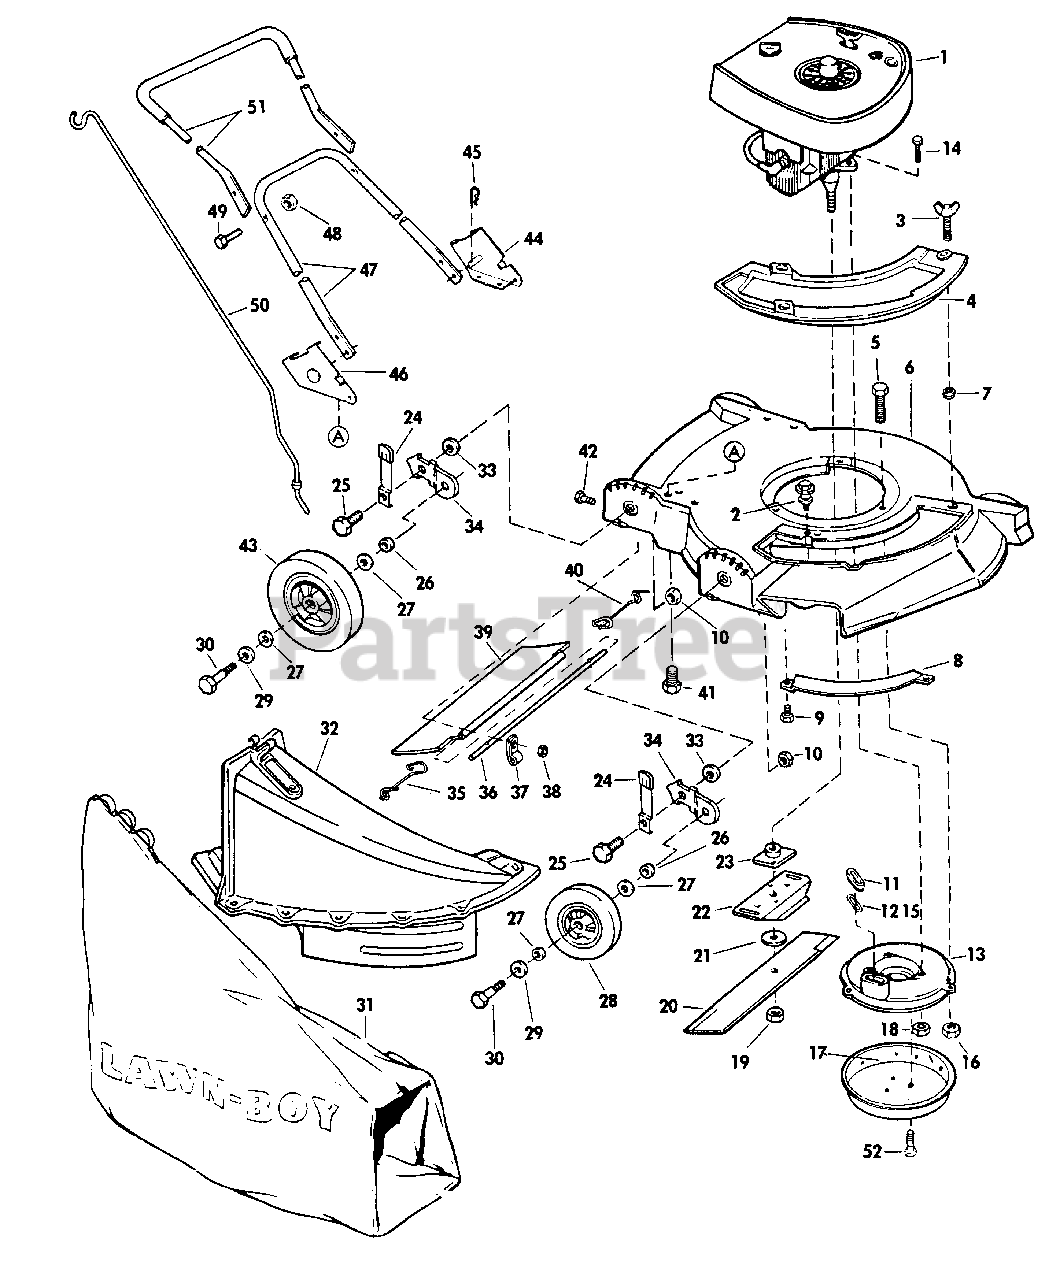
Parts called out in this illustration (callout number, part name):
1	See Note #2 at bottom of this page.
2	Screw
3	Wing Screw
4	Cover-Chute Opening
5	Screw-Muffler Plate to Housing
6	Housing Assembly 19" Only
6	Housing Assembly 21" Only
7	Grommet
8	Toe Bar
9	Screw
10	Nut
11	Sleeve-Muffler Gasket
12	Gasket-Exhaust
13	Muffler Plate
14	Screw
15	Gasket-Muffler
16	Nut-Nylok
17	Muffler-Cover
18	Nut-Muffler
19	Nut-Blade
20	Blade-21" Only
21	Blade-19" Only
21	Washer-21" Only
22	Stiffener-Blade
23	Collar & Plate Assembly
24	Knob & Spring Ay.
25	Bolt-Wheel Brkt. to Knob & Spring Ay.
26	Washer
27	Felt Washer
28	Wheel & Tire Assembly-6"
29	Washer-Wheel Bolt Head
30	Bolt-Shoulder, Wheel
31	Bag
32	Chute Assembly
33	Washer-Whl. Brkt. Mtg.
34	Wheel Hgt. Adj. Brkt.
35	Spring-R.H.
36	Rod
37	Clamp
38	Nut
39	Shield
40	Spring-L.H.
41	Screw-Handle Bracket
42	Screw
43	Wheel & Tire Assembly-8"
44	Bracket-Handle, Left
45	Hairpin
46	Bracket-Handle, Right
47	Handle-Bottom
48	Nut-Handle
49	Screw-Handle
50	Bag Rod
51	Handle and Grip Assembly-Top
52	Bolt, Muffler
